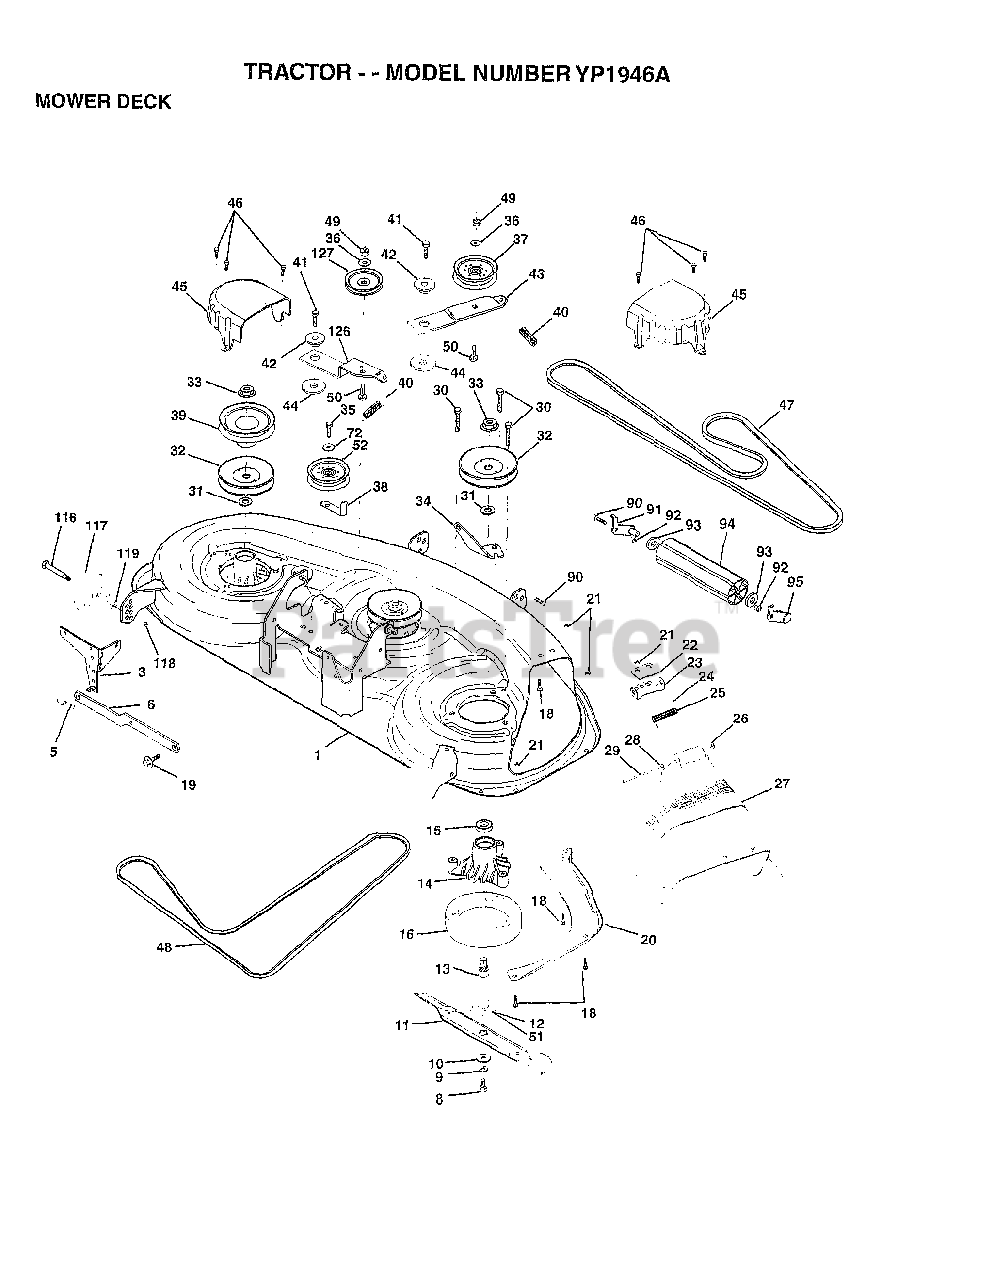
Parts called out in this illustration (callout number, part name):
1	"MOWER ASM 46"""
3	BRKT.ASM.SW.44/50
8	BLADE BOLT
10	WASHER.HARD.BLADE
12	BEARING.BALL
13	SHAFT.ASM.W/BRNG
14	HOUSING.MAND.44.V
15	BEARING
16	STRIPPER RND MWR
18	BOLT
19	BOLT SHD 5/16-18
20	BAFFFLE.VORTEX.46
22	STIFFENER BRKT
23	DEFLECTOR BRKT
24	CAP-SLEEVE LT
25	SPRING TORSION
27	SHIELD DEFLECTOR
28	WASHER
29	HINGE ROD
31	WASHER
32	PULLEY.MAND.36/46
34	ANCHOR.SPRING.46
35	SCREW LT
36	WASHER
37	FLAT IDLER PULLEY
38	"KEEPER BELT,IDLER"
39	PULLEY.DRV.DCK.46
40	"SPRING.SEC.44""VEN"
41	SCREW
42	SPACER RETAINER
43	ARM.IDLER.DECK.46
44	HARDENED WASHER
45	COVER.MANDREL.46
46	SCREW.1/4-20X5/8
47	BELT-V.SEC.46.KEL
48	BELT V PRIM 50
50	BOLT.3/8-16X1.50
51	WASHER.FELT.
52	"PULLEY IDLER,FLAT"
72	WASHER HYT
90	BOLT
91	Roller Bracket Assembly, LH
92	NUT
93	WASHER
116	BOLT.SHOULDER
117	WHEEL GAGE DONUT
118	LOCKNUT
119	WASHER
126	ARM.IDLER.PRIM.46
127	PULLEY.IDLER.4.25
